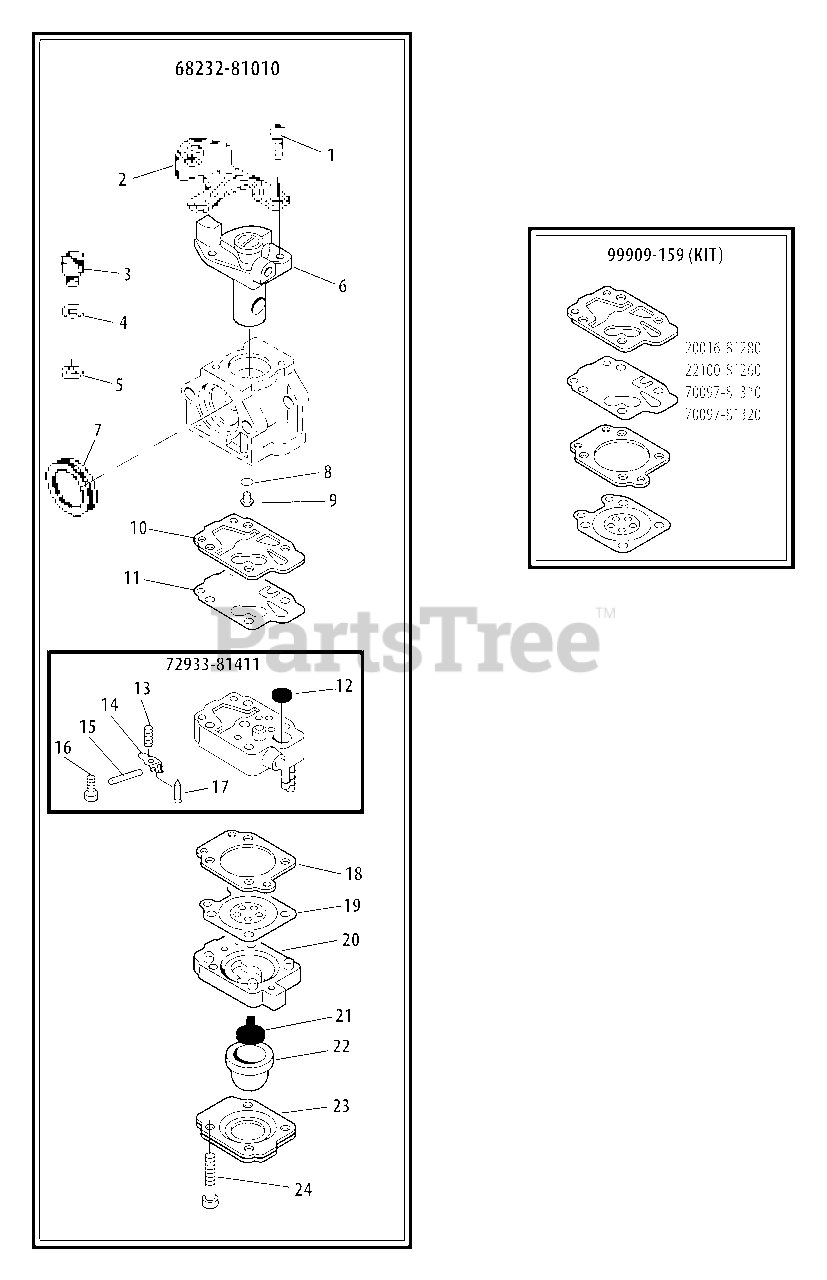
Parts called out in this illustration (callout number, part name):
1	SCREW
2	BRACKET, CABLE
3	SWIVEL
4	WASHER
5	RING, RETAINING
6	THROTTLE VALVE ASSY
7	SEAL
8	O-RING
9	MAIN JET (#48)
10	GASKET, PUMP
11	DIAPHRAGM, PUMP
12	STRAINER
13	SPRING, METERING LEVER
14	LEVER, METERING
15	PIN, METERING LEVER
16	SCREW, METERING LEVER PIN
17	VALVE, INLET NEEDLE
18	GASKET, METERING
19	DIAPHRAGM, METERING
20	BASE, PURGE
21	VALVE, CHECK
22	BULB, PURGE
23	RETAINER, PURGE BULB
24	SCREW, PUMP COVER
68232-81010	CARBURETOR
72933-81411	BASE, PURGE
99909-159	DIAPHRAGM/GASKET KIT
